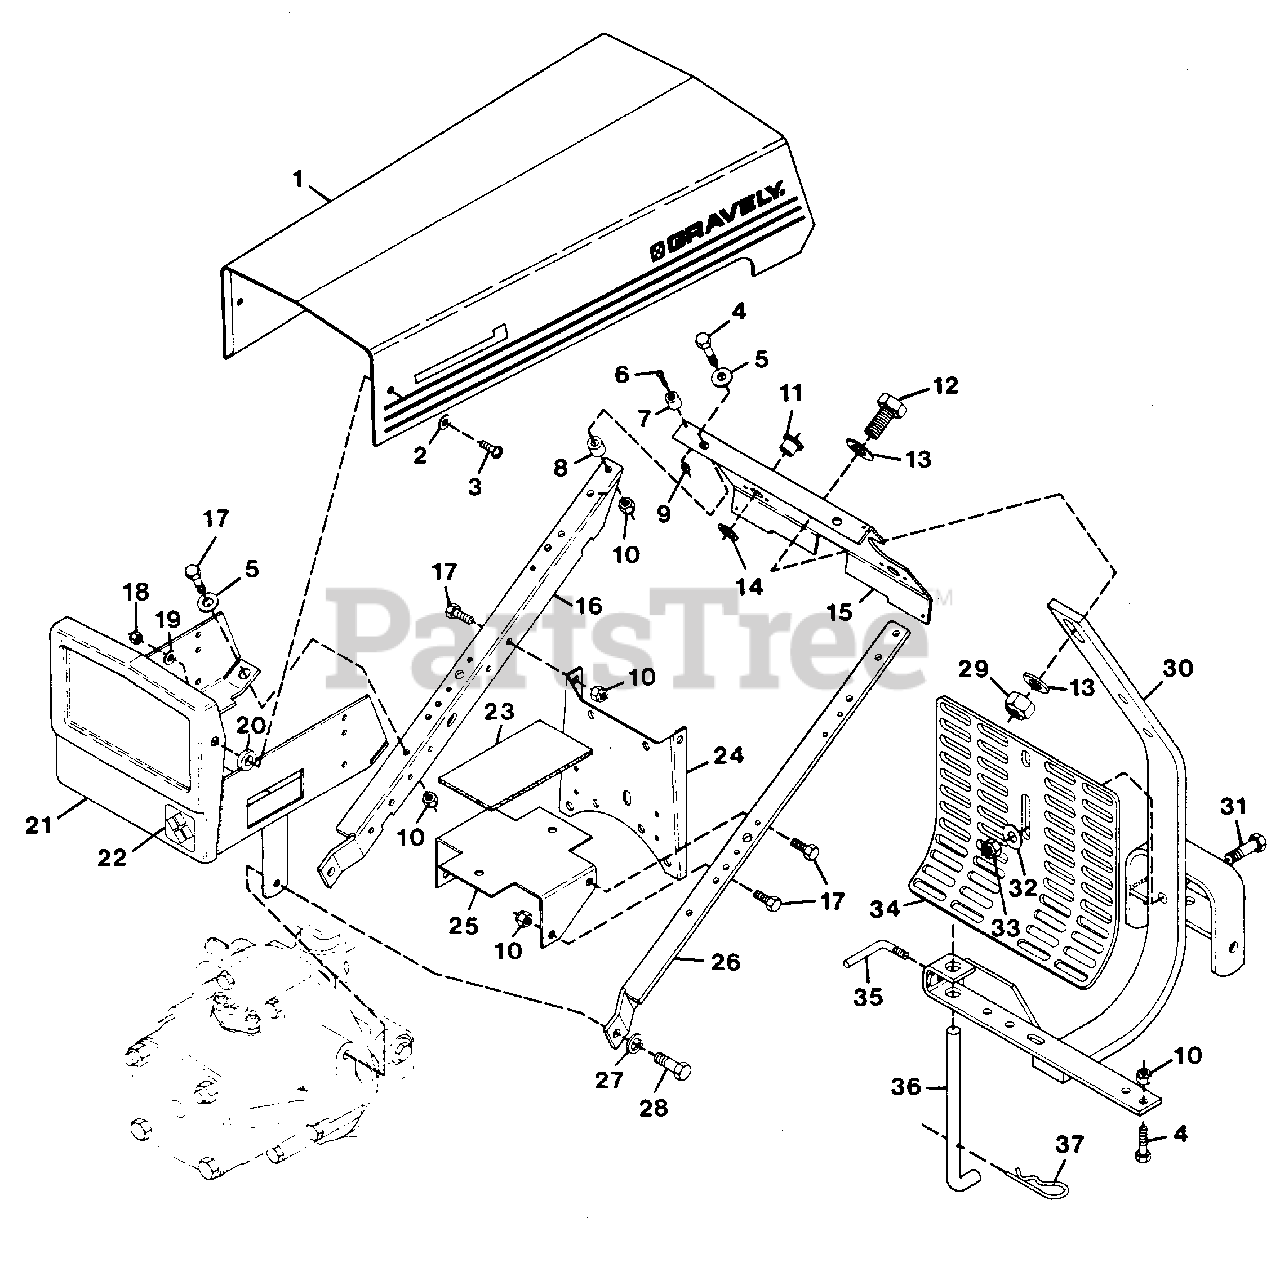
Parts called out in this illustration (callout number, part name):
1	ASSEMBLY, HOOD
2	WASHER, FLAT .281X.625X.065
3	SCREW, MACH. 1/4-20X1.00 PHD
4	BOLT, HEX 3/8-16X1.50
5	WASHER, FLAT .406X.812X.065
6	SCREW, MACH. 6-32X.625 PHD
7	BUMPER
8	BUSHING, REVERSE IDLER
9	NUT, MACH. LOCK 6-32
10	NUT, LOCK 3/8-16
11	BUSHING, .513X.750X.625
12	BOLT, HEX 5/8-11X2.00
13	WASHER, FLAT .656X1.250X.100
14	RING, RETAINING
15	PLATE, SILK SCREEN
16	SUPPORT, HANDLEBAR R.H.
17	BOLT, HEX 3/8-16X.875
18	NUT, LOCK 1/4-20
19	WASHER, FLAT .313X.875X.065
20	BUSHING, HOOD
21	WELDMENT, BATTERY BRACKET
22	DECAL
23	PAD, GAS TANK
24	BRACKET
25	BRACKET, TANK SUPPORT
26	SUPPORT, HANDLEBAR L.H.
27	WASHER, LOCK 1/2 REG.
28	BOLT, HEX 1/2-13X1.00
29	NUT, LOCK 5/8-11
30	WELDMENT, HITCH 10 AND 12 H.P.
31	BOLT, HEX 1/2-13X1.50
32	WASHER, FLAT .531X1.250X.100
33	NUT, LOCK 1/2-13
34	GUARD, ENGINE
35	HANDLE, ADJUSTING
36	STAND, KICK
37	PIN, HAIR
NS	DECAL, 10
NS	DECAL, 12
NS	DECAL, 16
NS	DECAL, SIDE STRIPE
NS	DECAL, GRAVELY LOGO
NS	DECAL, 6 LEAD
NS	DECAL, 8 LEAD
NS	DECAL, PROFESSIONAL
